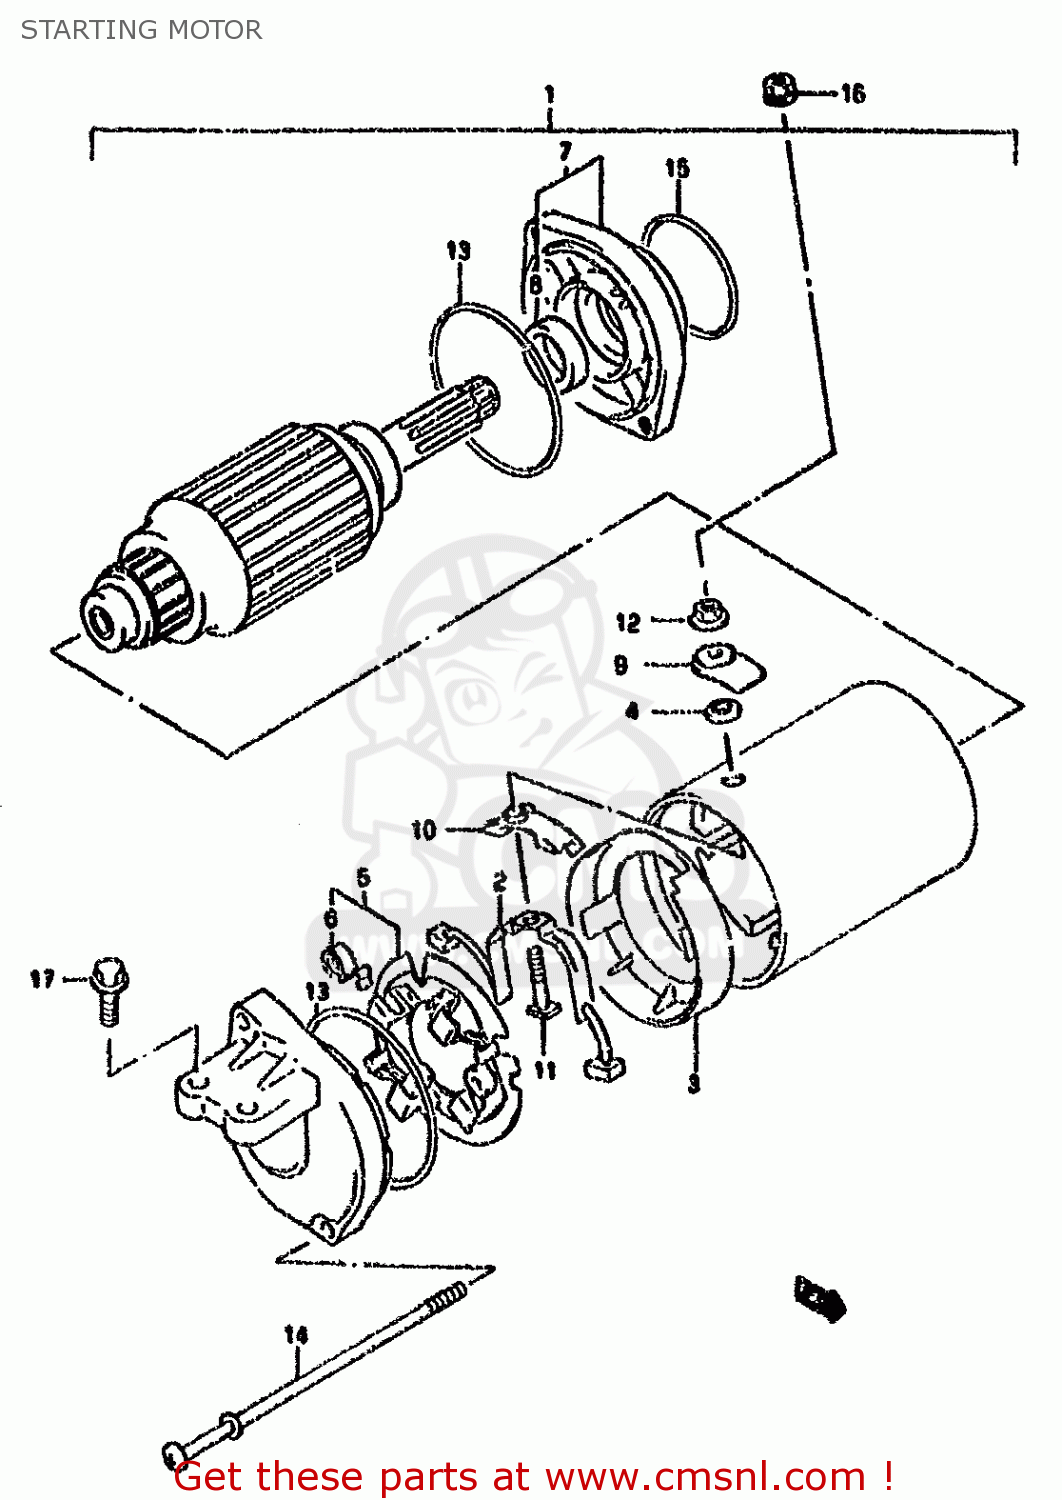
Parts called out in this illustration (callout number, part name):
1	MOTOR ASSY, STARTING
2	TERMINAL SET,BRUSH
3	INSULATOR
4	GASKET (NAS)
5	HOLDER SET,BRUSH(-)
6	SPRING
7	BRACKET SET
8	SEAL,OIL
9	BUSHING
10	BUSHING
11	BOLT
12	NUT
13	O RING
14	BOLT
15	O-RING (D:2.0)
16	NUT
17	BOLT
